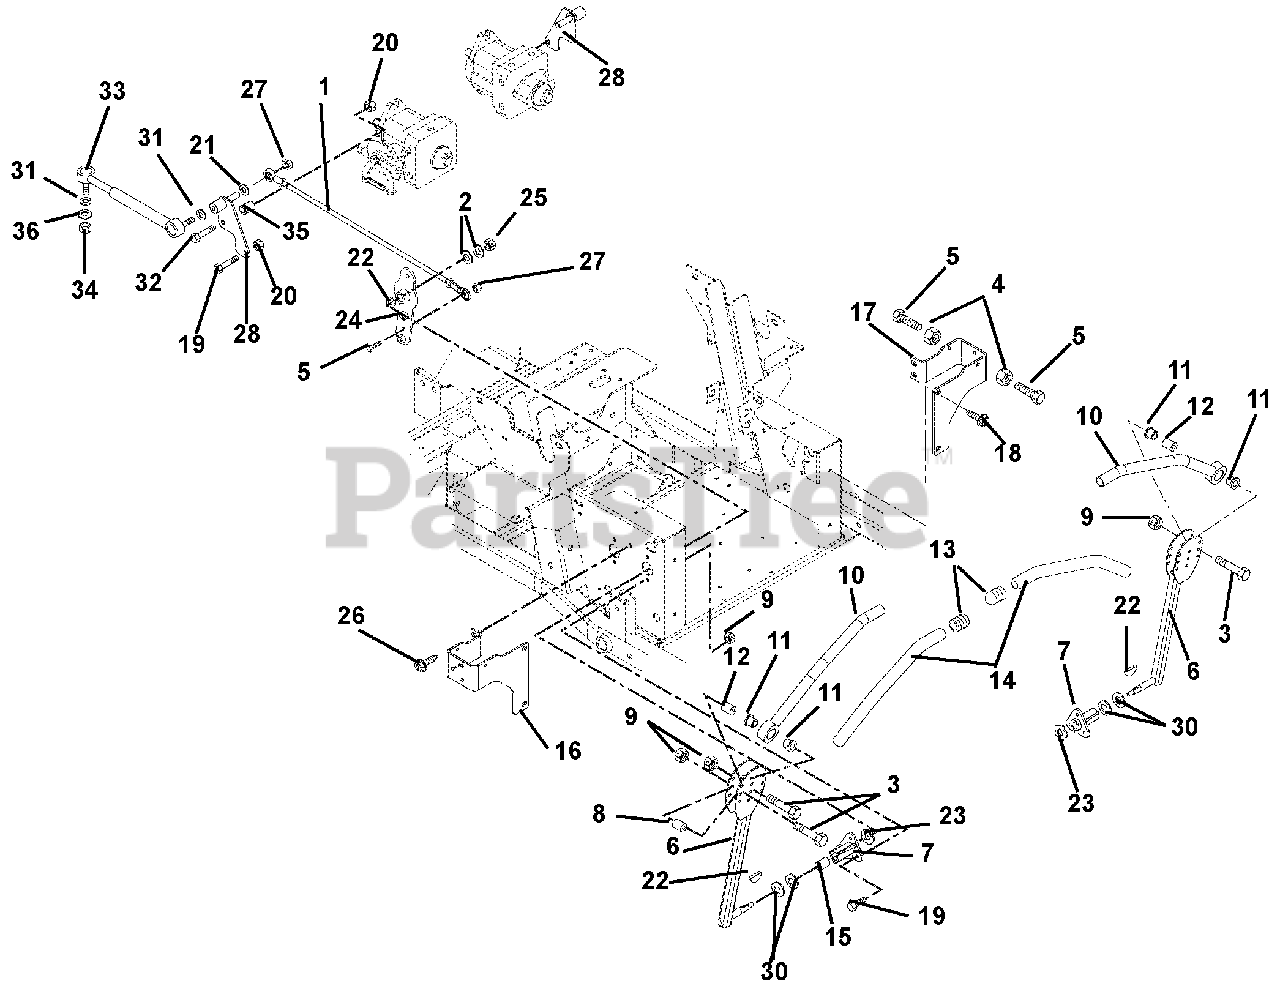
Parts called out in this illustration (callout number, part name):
1	Assembly, Steering Rod .38Rod x 21.65
2	Washer, Flat Steel .408 x .812 x .065
3	Bolt, Hex .31-18 x 1.75 Grade 5
4	Nut, Hex Jam .375-16
5	Bolt, Hex .375-16 x 1.75
6	Weldment, Control Arm
7	Bushing, Flange
8	Eccentric
9	Nut, Locking Top Flange .31-18
10	Handle Weldment-Left Hand
11	Bushing, Flange Nylon .762 x 1.48 x .44
13	Caplug, Handlebar
14	Grip, Handlebar
15	Bushing .625 x .75 x .50
16	Bracket, Stop Right Hand
17	Bracket, Stop Left Hand
18	Screw, Tapping .38-16 x .75 Hex Washer Head
19	Bolt, Hex .31-18 x .75 Grade 5
20	Nut, Locking Top Flange .31-18
21	Washer, Locking .38 x .094 Regular
22	Key, Woodruff .13 x .63
23	Washer, Wave
24	Weldment, Pivot Arm
25	Nut, Locking Top Flange .38-16
26	Screw, Tapping .38-16 x .50 Hex Washer Head
27	Nut, Locking Jam Center .375-16
28	Weldment, Return to Neutral/Damper/Rod End
29	Bolt, Hex .38-16 x 1.25 Grade 5
30	Washer, Flat Steel .63 x 1.005 x .062
31	Washer, Locking .31 x .078
32	Bolt-Hex .31-18 x 1.25 Grade 5
33	Damper, Control
34	Nut-Locking-Nylon M8-1.25
35	Spacer .318 x .43 x .375
36	Washer, Flat Steel .38 x .875 x .083
